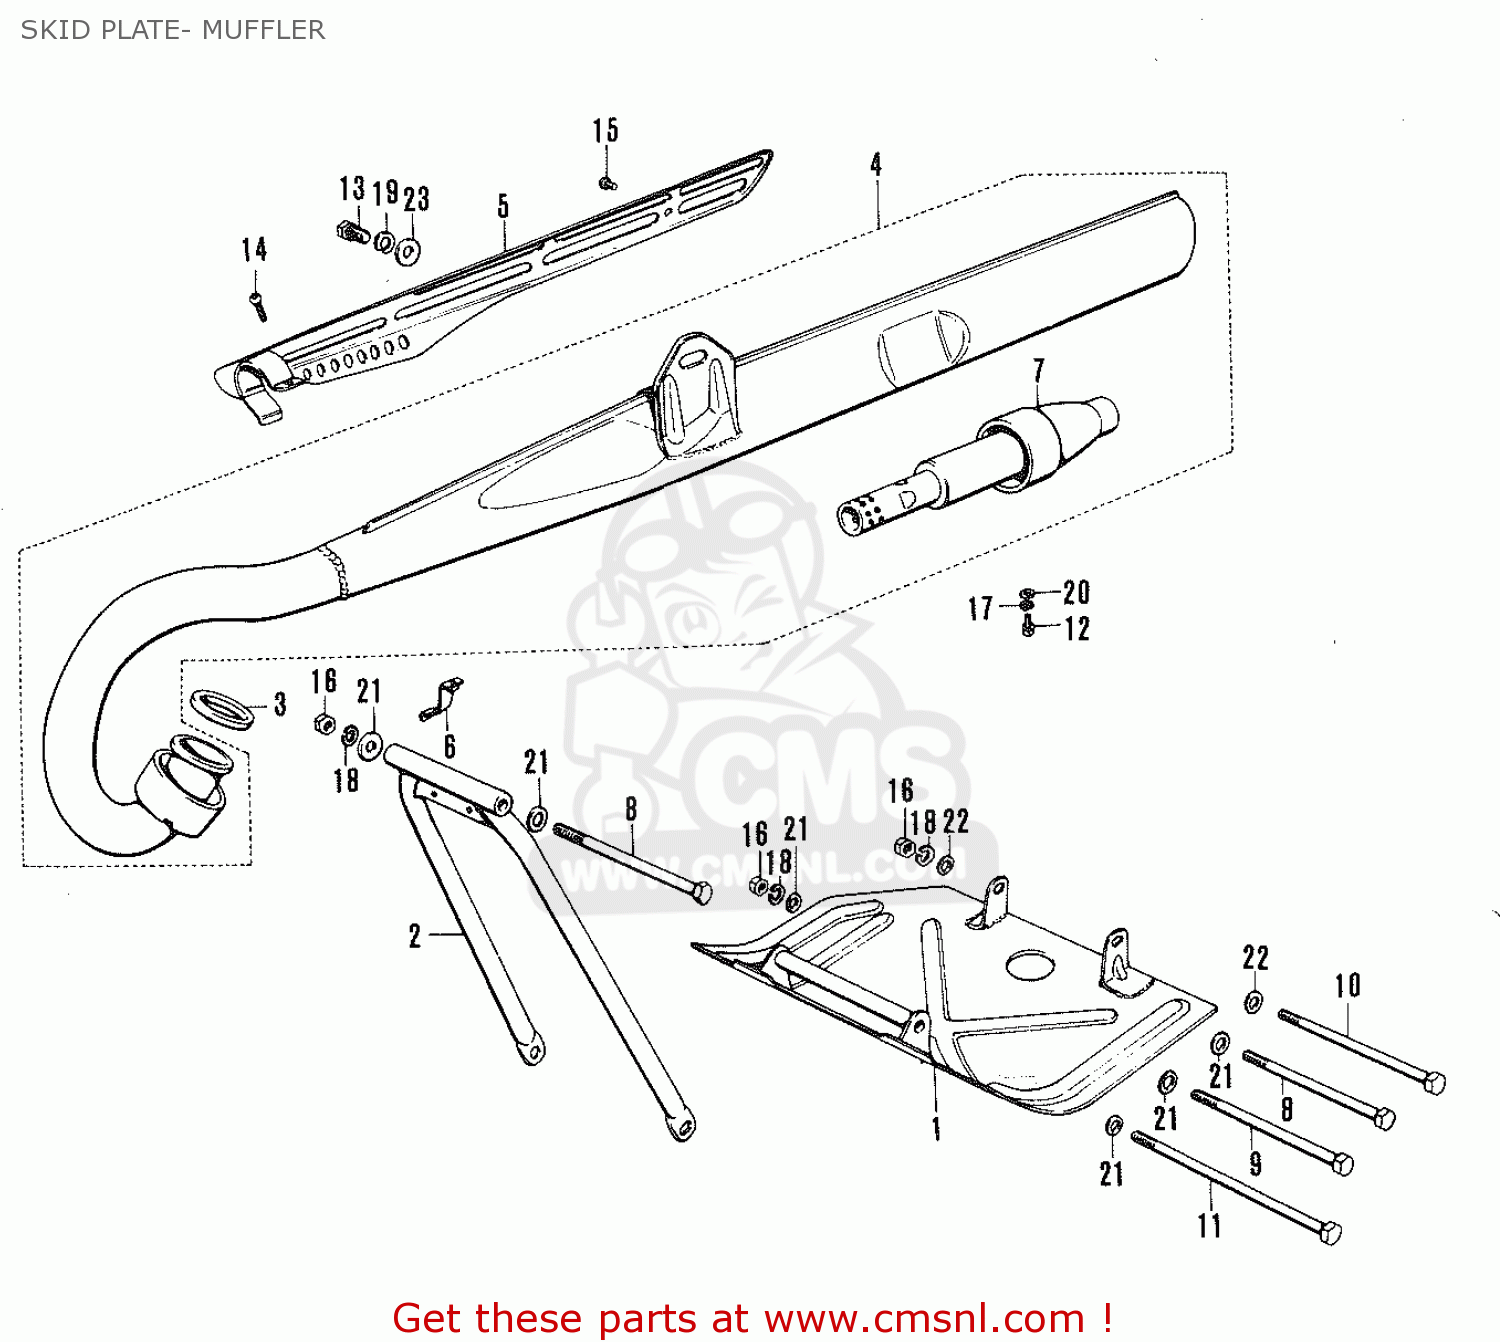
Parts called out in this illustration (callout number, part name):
1	GROMMET
2	BRACE
3	GASKET,EXHAUST PIPE (NAS)
4	MUFFLER ASSEMBLY
5	COVER,MUFFLER
6	MUFFLER COVER CLAMP
7	SPARK ARRESTER
8	BOLT 8X110
9	BOLT
10	BOLT 8X125
11	BOLT
12	HEXAGON BOLT
13	BOLT
14	SCREW
15	SCREW
16	NUT
17	LOCK WASHER
18	LOCK WASHER
19	LOCK WASHER
20	WASHER 6MM
21	WASHER
22	WASHER
23	WASHER
